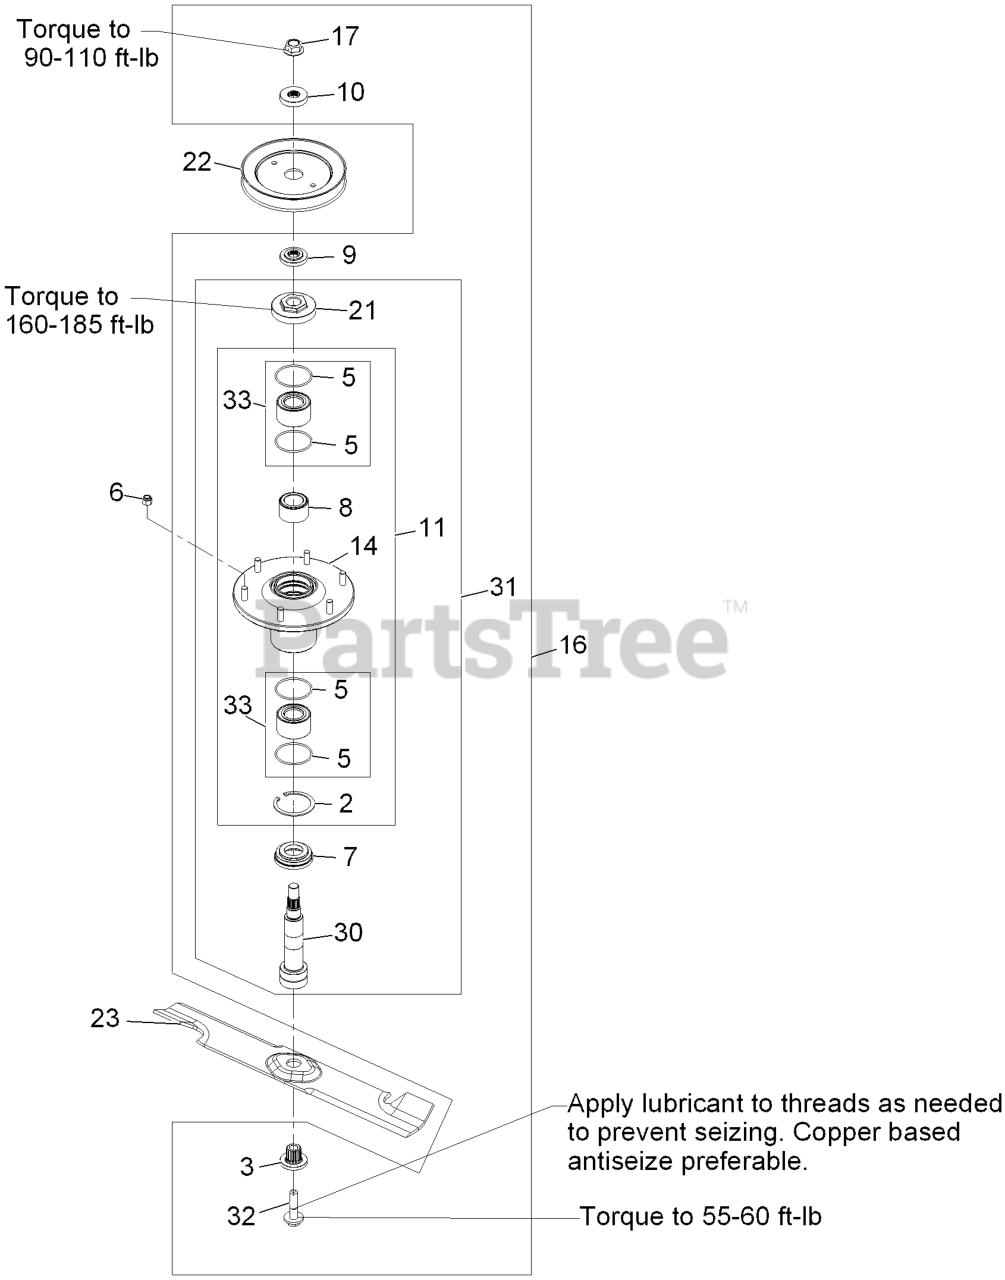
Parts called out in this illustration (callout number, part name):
2	RING-RETAINING
3	BUSHING,SPLINED
6	NUT-LOCK, NI
7	GUARD,BOTTOM
8	SPACER,BEARING
9	SPACER,SPLINED STEPPED
10	SPACER,SPLINED
11	ASM,CUTTER HOUSING
14	ASM,HOUSING W/STUDS
16	ASM, CUTTER HSG W/MNT HRD
17	NUT-FLANGE, CENTERLOCK
21	NUT, SPINDLE 7/8-14
22	SHEAVE, BLADE DRIVE 6.13
23	Blade,High Lift Notched 20.75
30	SPINDLE,DOUBLE SPLINE
31	ASM,SPINDLE HOUSING
32	SCREW,SEMS 1/2-20 X 2.19
33	ASM, BEARING W/ORINGS
